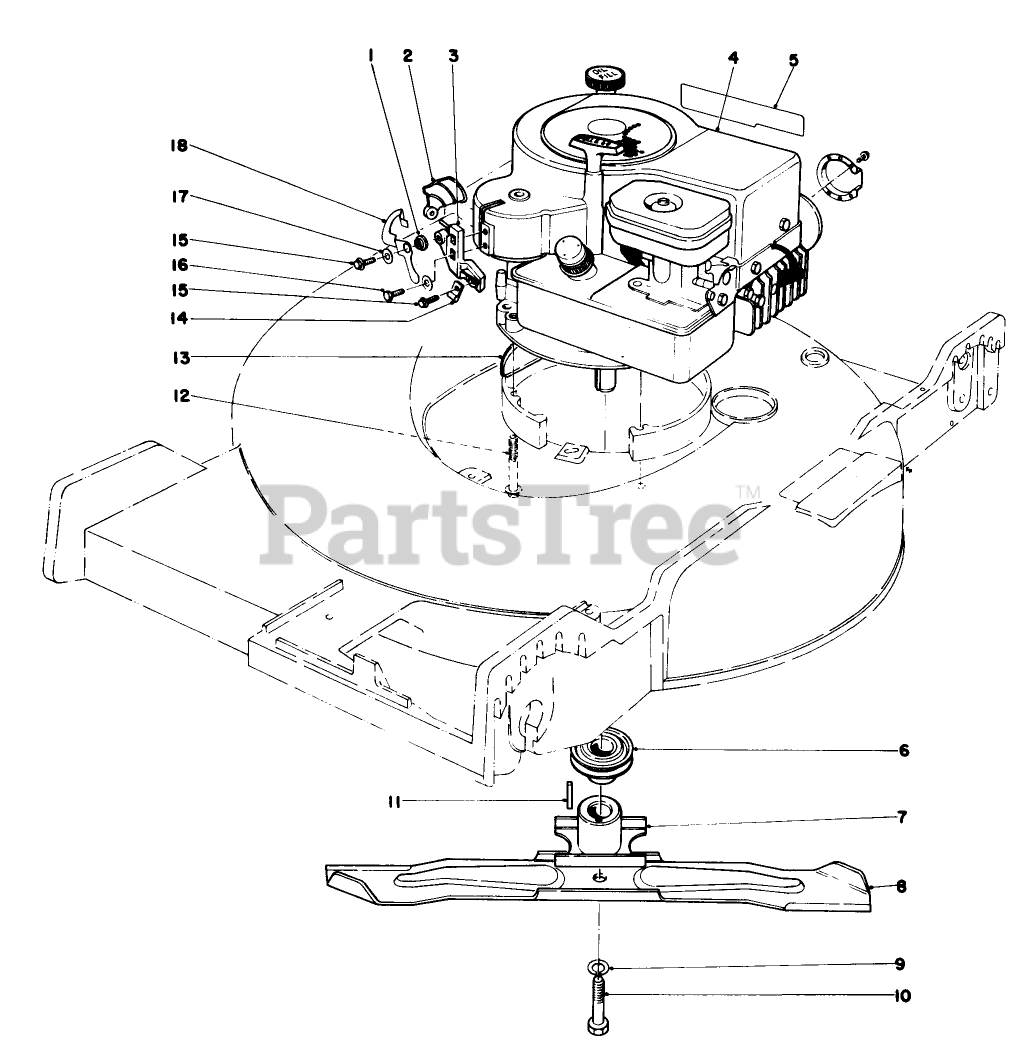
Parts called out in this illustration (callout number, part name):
1	BUSHING
2	INTERLOCK LEVER
4	Engine
9	WASHER-LOCK
10	BLADE SCREW
11	KEY-SQUARE
12	3/8-16 X 2-3/4 CAPSCR
13	HOUSING CAP
15	SCREW-HWHTF
16	SCREW-SHWH
17	WASHER-FLAT
